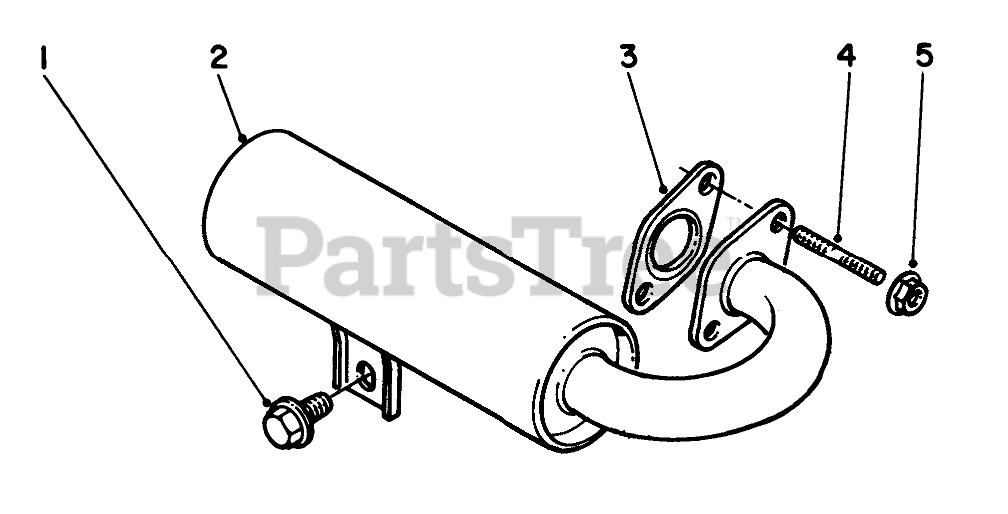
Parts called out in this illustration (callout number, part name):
2	Muffler
3	Gasket
4	Bolt-Stud
